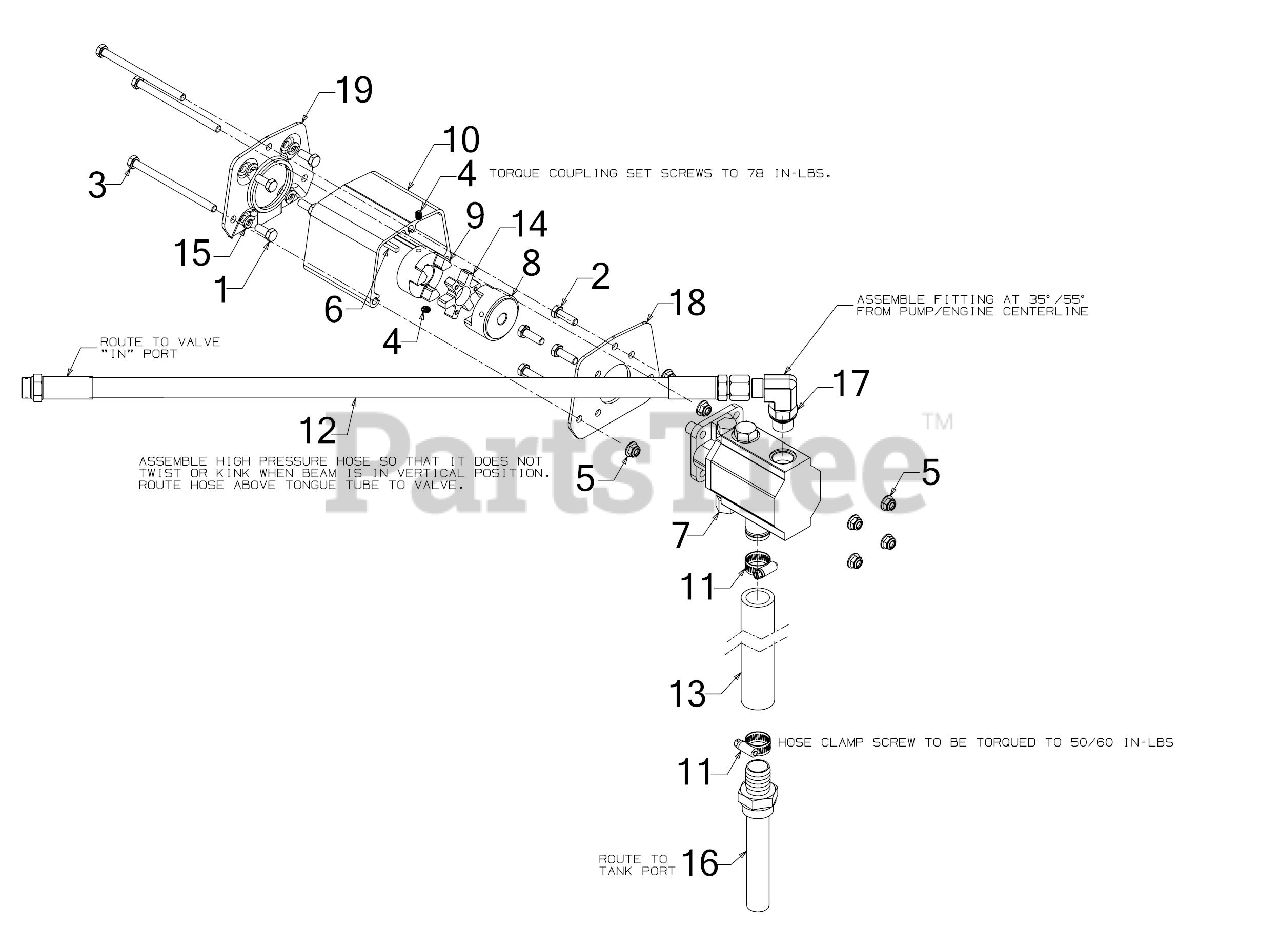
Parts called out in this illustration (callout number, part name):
1	HEX SCREW 5/16-24 x .75
2	SCREW 5/16-18 x 1.0 GR5
3	SCREW 5/16-18 x 4.750 GR5
4	SCREW 1/4-20 x .38
5	FLANGE LOCK NUT 5/16-18
6	SQUARE KEY 3/16 x .7
7	LOGSPLITTER GEAR PUMP 16GPM
8	LOGSPLITTER COUPLING .500
9	LOGSPLITTER COUPLING .875
10	COUPLING SHIELD
11	HOSE CLAMP-5/8
12	48" HYDRAULIC HOSE
13	SUCTION HOSE
14	SPIDER COUPLING BUSHING
15	LOCK WASHER 5/16
16	INLET FILTER
17	90 DEGREE HYDRO FITTING 7/8 ORB x 13/16
18	SUPPORT BRACKET
